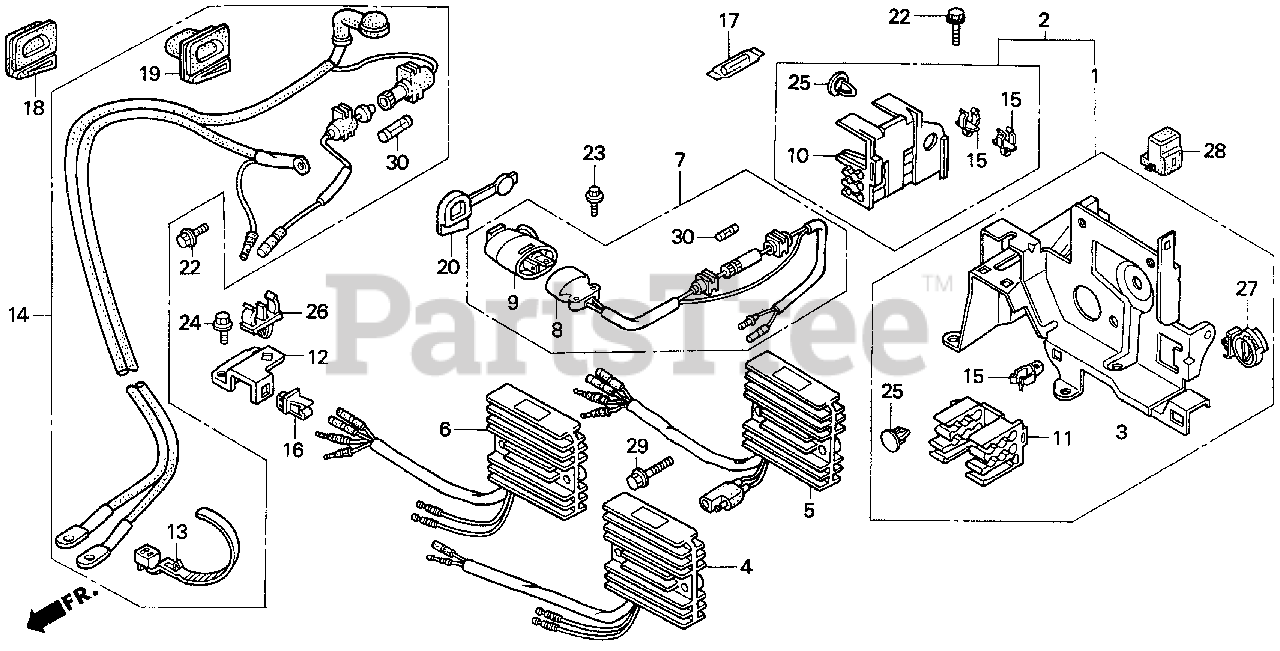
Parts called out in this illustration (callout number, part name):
1	BRACKET ASSY., NEUTRAL STARTING CABLE
11	BRACKET, CONNECTOR (B)
15	CLIP, WIRE
18	GROMMET C, OIL CASE
22	BOLT, FLANGE (6X12)
25	CLIP, ANCHOR
27	CLIP, WIRE HARNESS
28	CAP (090 2P)
